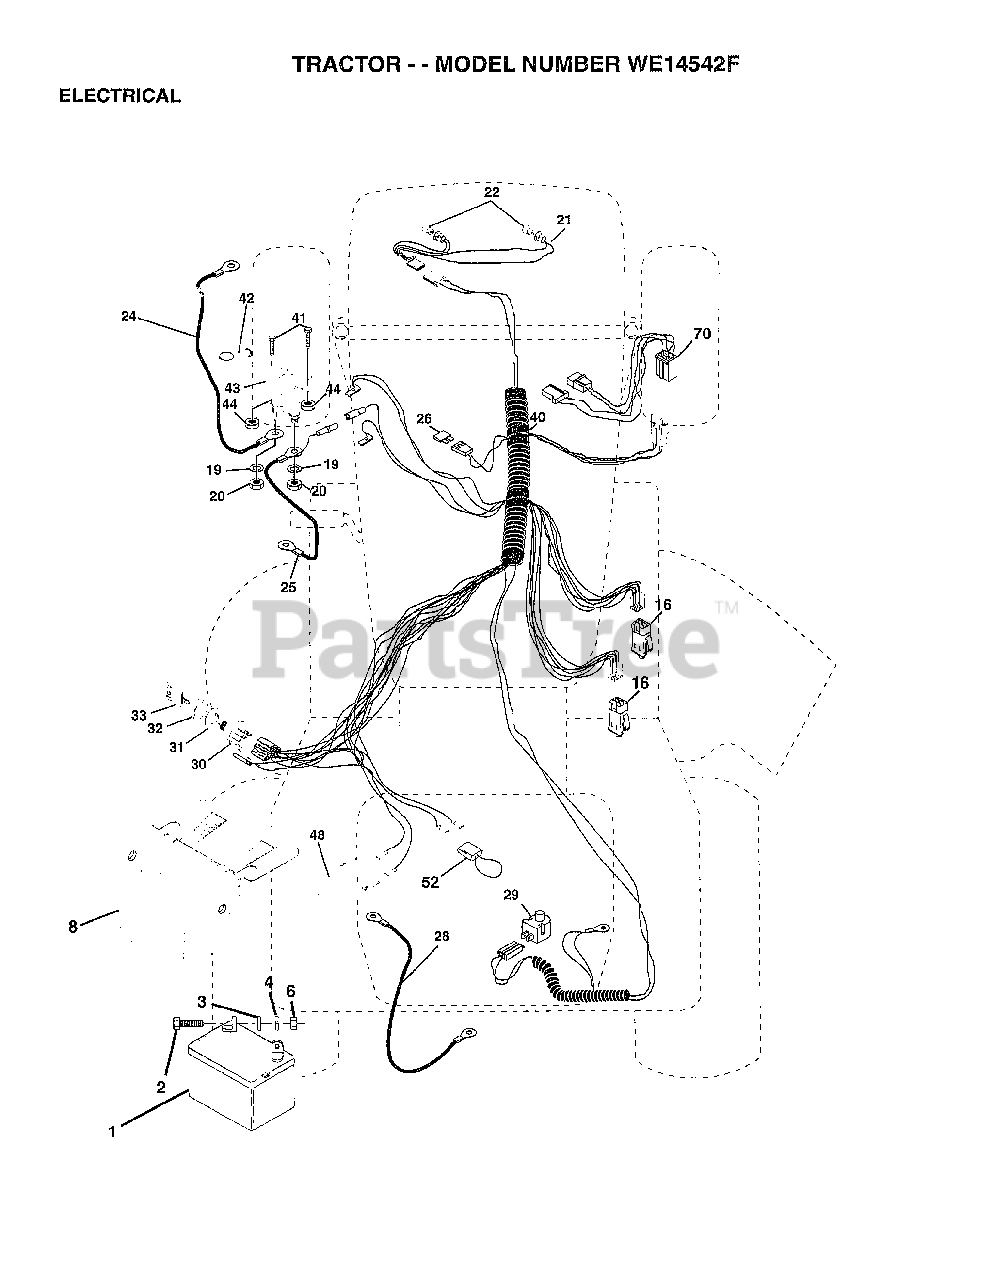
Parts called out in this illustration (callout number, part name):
2	BOLT LT
3	WASHER
4	LOCKWASHER
8	"CASE,BATTERY.MECH"
16	SWITCH INTERLOCK
20	NUT
21	"HARNESS,LIGHT SOC"
22	HEADLAMP BULB
24	"CABLE T, BATTERY"
25	CABLE.BTRY.6GA.RD
26	FUSE HYT
28	CABLE T
29	SWITCH SEAT
30	SWITCH IGN 4POS
31	NUT IGNITION
32	COVER KEY SWITCH
33	KEY
40	HARNESS-IGNITION
41	BOLT HXHD FIN
44	NUT HXKEP 1/4X20
48	ADAPTER AMMETER
52	PROTECTION LOOP
70	HARNESS.ENG.DUAL
